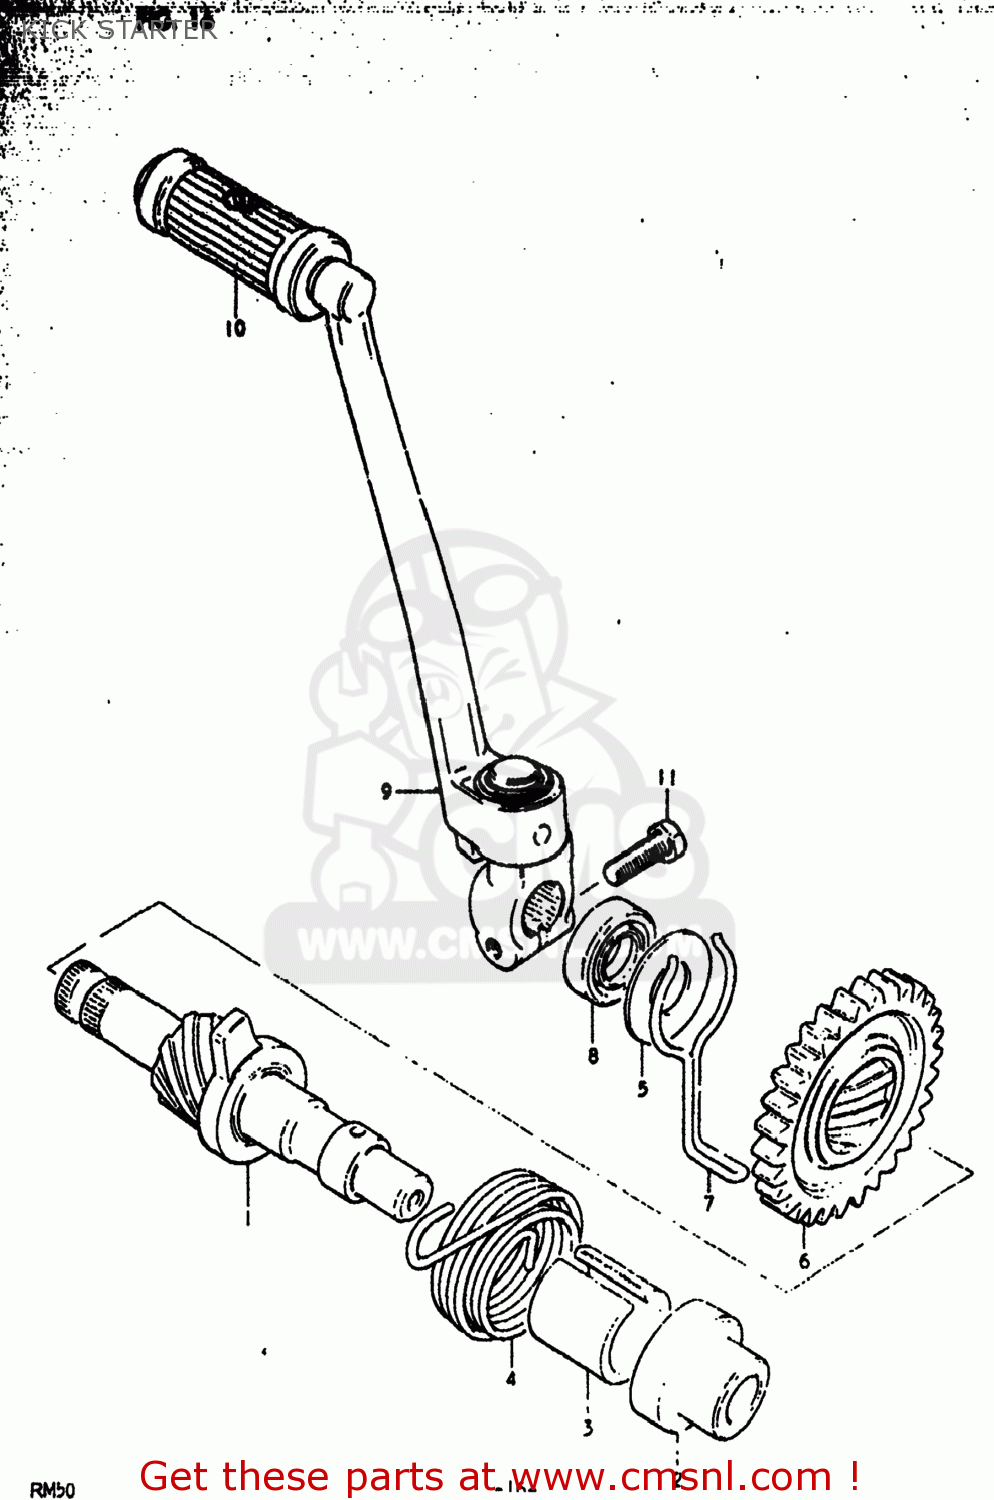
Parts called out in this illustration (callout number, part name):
1	SHAFT,KICK STARTER
2	HOLDER,KICK STARTER SHAFT
3	GUIDE,KICK STARTER SFT SPRING
4	SPRING
5	WASHER
6	GEAR,KICK STARTER DRIVE(NT:30)
7	RETAINER,SNAP
8	SEAL,OIL(14X24X6)
9	LEVER ASSEMBLY,KICK STARTER
10	RUBBER,KICK STARTER PEDAL
11	BOLT
